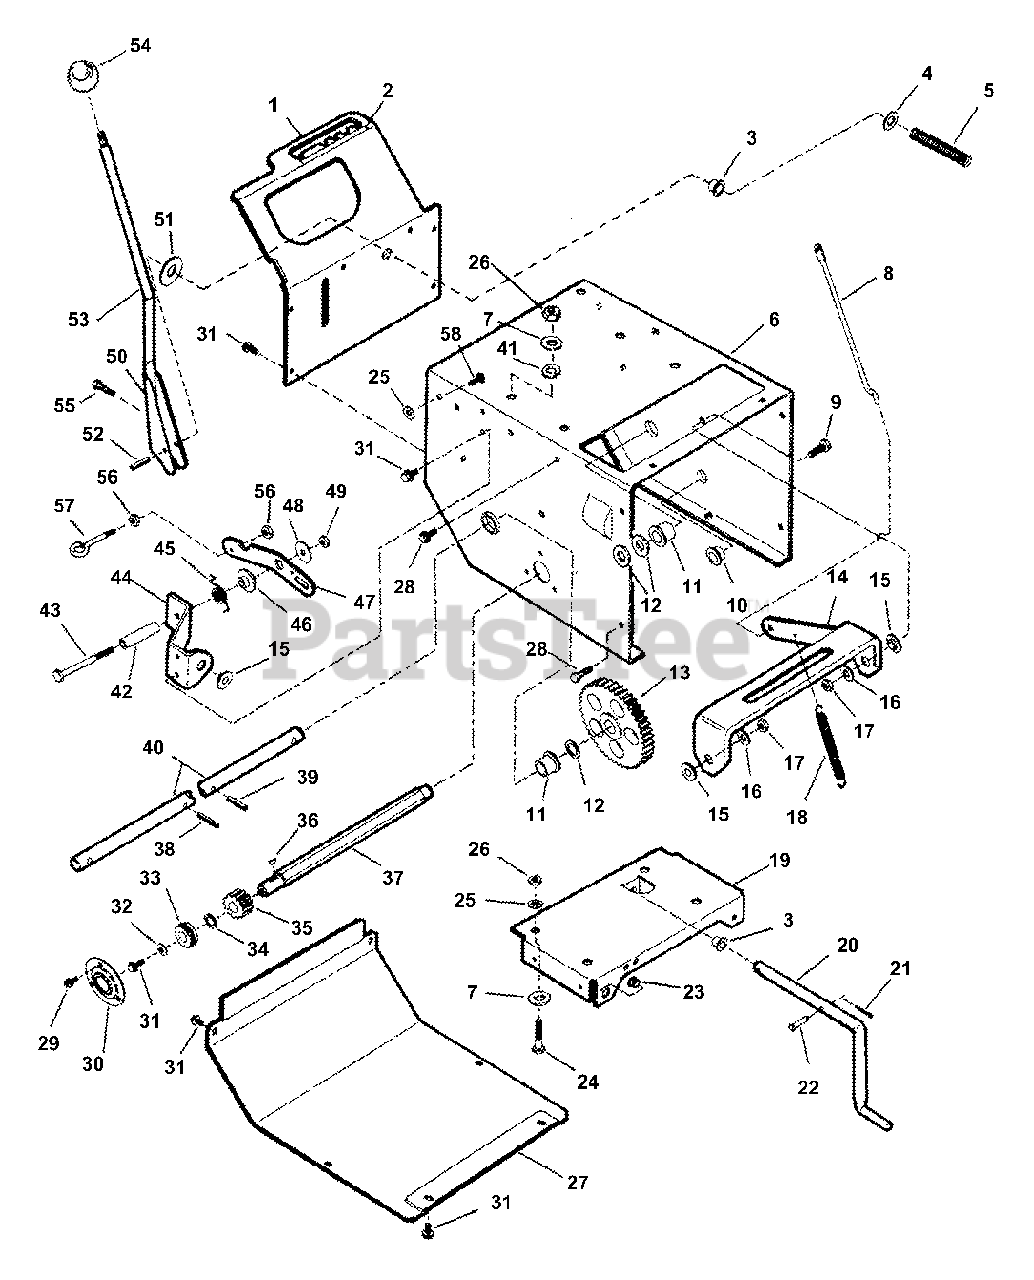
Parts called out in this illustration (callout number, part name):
1	COVER, Rear Frame & Shift Detent
2	DECAL, Direction Control
3	BUSHING, 1/2" Nylon
4	WASHER, 1/2" Flat
5	SPRING, Shift
7	WASHER, 5/16" Flat
8	ROD, Clutch
9	SCREW, 3/8-16 x 1" Hex Head Cap, Grade 5
10	BEARING
11	BUSHING
12	WASHER, 3/4" Flat
13	GEAR, Axle Shaft
14	BRACKET, Clutch
15	BUSHING
16	WASHER, 3/8" Flat
17	NUT, 3/8-16 Hex Center Lock, Grade B or 5
18	SPRING, Clutch
19	SUPPORT, Engine
20	ROD, Shift
21	PIN, 1/16 x 1/2" Cotter
22	PIN, 3/16 x 7/8" Clevis
23	BUSHING, 3/8" Plastic
24	BOLT, 5/16-18 x 1-3/4" Hex Tap, Grade 5
25	RETAINER, 5/16" Bolt
26	NUT, 5/16-18 Hex, Grade 5
27	COVER, Bottom Frame
28	SCREW, 5/16-18 x 1/2" Hex Washer Self-Tap
29	SCREW, #10-32 x 1/4" Hex Washer Self-Tap
30	RETAINER, Bearing
31	SCREW, 1/4-20 x 1/2" Hex Washer Self-Tap
32	WASHER, 1/4" Flat
33	BEARING, Ball
34	WASHER, 1/2" Shim
35	GEAR, Pinion
36	KEY, 3/32 x 1/2 Woodruff (#304)
37	SHAFT, Hex
38	PIN, 1/4 x 1-1/4" Roll
39	PIN, 1/4 x 1" Roll
40	AXLE, Shaft
41	WASHER, 5/16" Split Lock
43	SCREW, 5/16-18 x 3" Hex Head Cap, Grade 5
44	BRACKET
45	SPRING
46	BUSHING
47	LEVER
48	WASHER, 5/16" Flat
49	NUT, 5/16-18 Hex Center Lock, Grade B
50	HUB, Shifter
51	WASHER, Thrust
52	PIN, 3/16 x 1" Roll
53	SHIFTER
54	KNOB, Shifter
55	SCREW, #10-32 x 5/8" Hex Washer Self-Tap
56	NUT, 1/4-20 Hex Flange Lock
57	BOLT, 1/4-20 Eye
58	BOLT, 5/16-18 x 5/8" Short Neck Carriage, Grade 5
